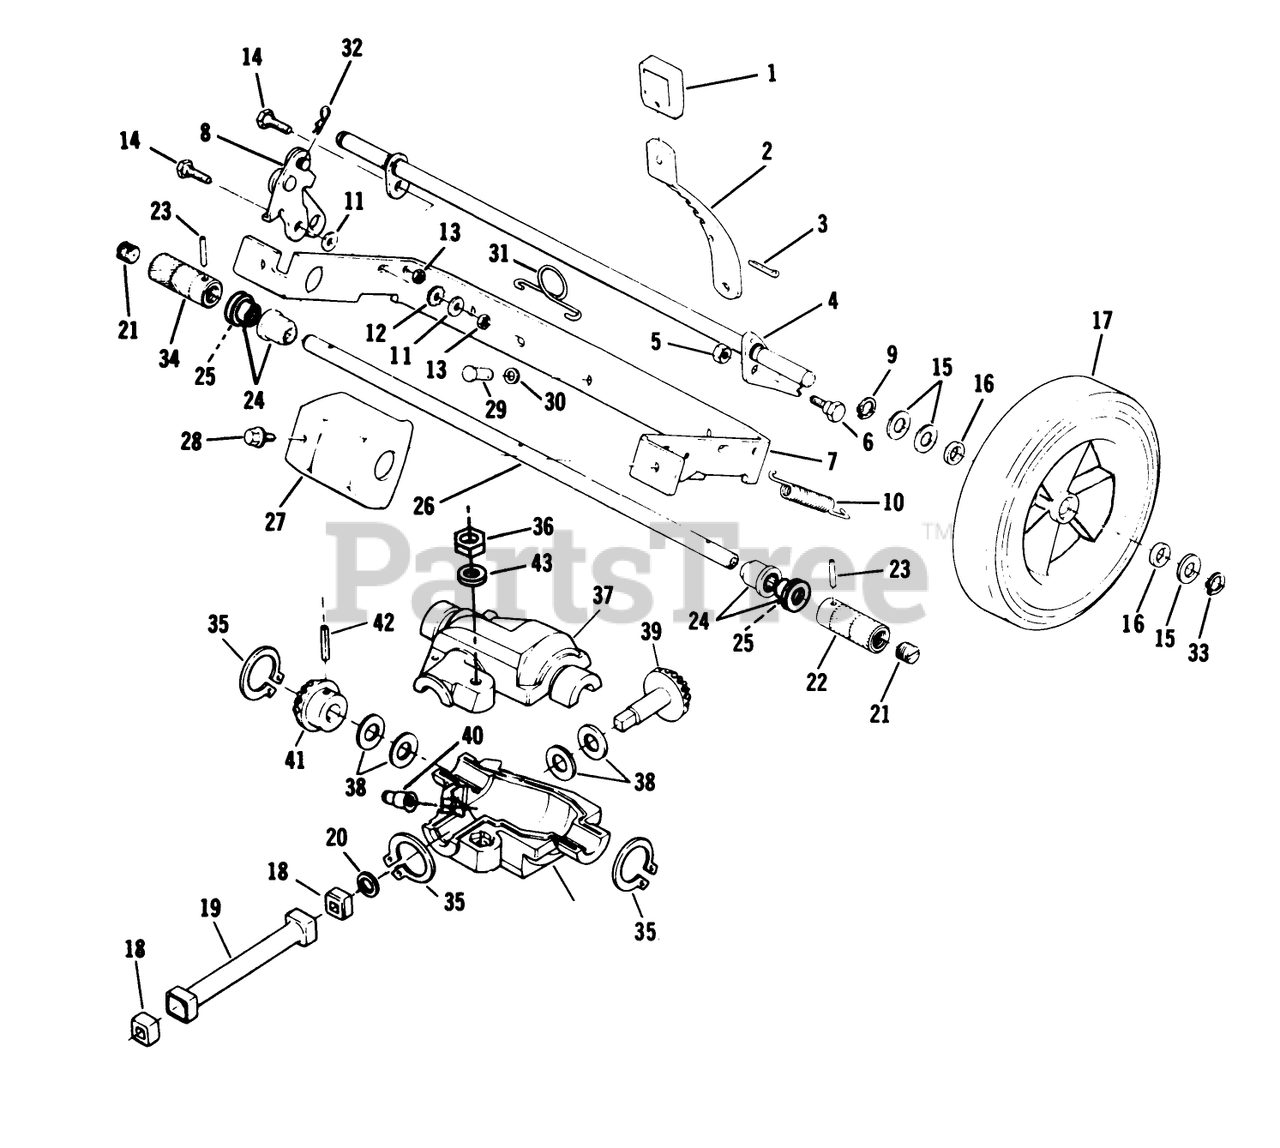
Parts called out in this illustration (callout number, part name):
1	KNOB
2	LEVER
5	LOCKNUT E
6	BOLT RB&W
7	BRK-21" AXLE
9	RET RING
10	SPRING
11	WASHER S
13	STOP NUT
14	BOLT RB&W
15	SPACER
16	WASHER
17	WHEEL & TIRE KIT
18	BUSHING
20	O-RING
21	GREASE PLUG
22	ROLLER (LEFT) VS
22	ROLLER-LH
24	SLEEVE &BEARING AY
25	P/M Bearing
26	DRIVE SHFT TAG AY
27	GUARD
29	PIN
30	WASHER SPRING LAR
31	SPRING N.A.S
33	RET RING
34	ROLLER (RIGHT) VS
34	ROLLER-RH
36	LOCKNUT E
37	GEARCASE AY-SERV
38	THRUST WASHER
39	GEAR BEST
40	ZERK FITTING
41	GEAR ADVANCE
42	ROLL PIN
43	WASHER F
